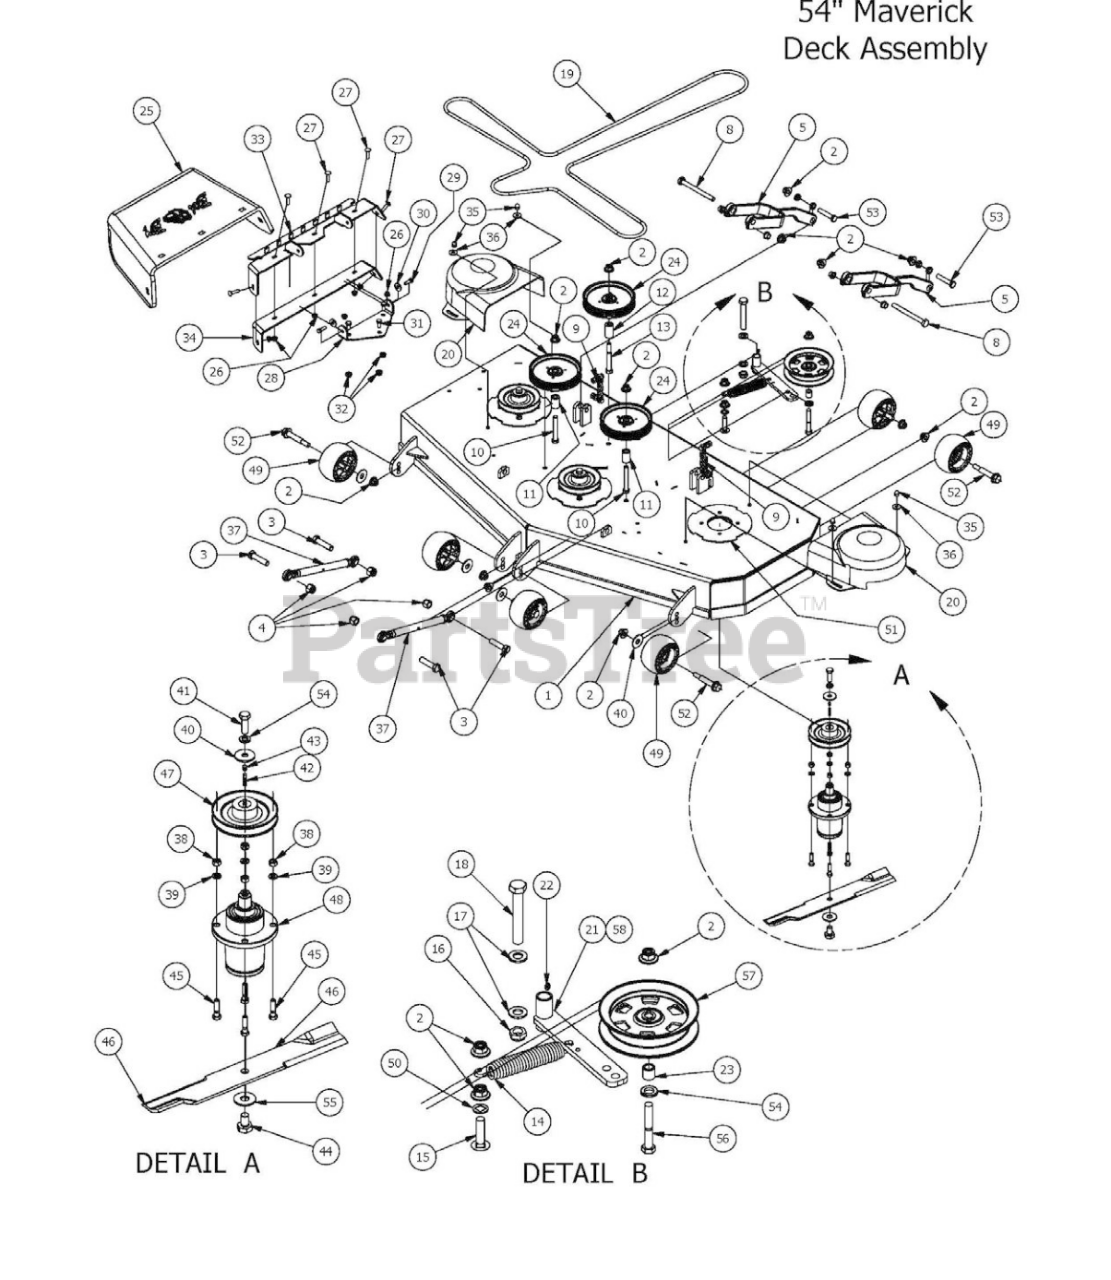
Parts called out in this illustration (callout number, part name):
1	Maverick 54" Deck
2	1/2-13 Nylon Flange Nut
3	5/8" x 2 1/2" Grade 5 Hex Bolt (Coarse)
4	5/8 Std NC Nylock Nut
5	Deck Arm Assembly
6	Flange Bushing For Lower Deck Arm
7	Flange Bushing For Upper Deck Arm
8	1/2" x 5 1/2" Bolt
9	6 Link Chain assembly
10	1/2 x 3 1/2 Flange Bolt Grade 8
11	Idler Pulley Standoff
12	1 3/4" Pulley Spacer
13	1/2" x 4" Bolt (Grade 8)
14	2015 Deck Idler Spring
15	1/2 x 2" Carriage Bolt
16	5/8-11 Nylon Insert Jam Half Nut
17	.630 ID Plastic Washer
18	5/8" x 4" Hex Bolt
19	B155.75 Deck Belt
20	2014 ZT Pulley Cover
21	Deck Idler
22	1/4" Drive in Grease Fitting
23	Spacer 3/4 OD x 1/2 ID x 314 Length
24	5-3/4 Idler Pulley
25	Rubber Discharge Chute
26	5/16" Nylon Flange Nut
27	5/16" x 1 1/4" Carriage Bolt
28	Discharge Chute Hanger (Deck Mounted)
29	5/16" x 1" Bolt
30	.360 ID Plastic Washer
31	3/8" x 3/4" Hex Bolt
32	3/8" Flange Nut
33	60" Discharge Chute Upper Hanger
34	60" Lower Hanger
35	Acorn nut-pulley Cover
36	.360 ID Plastic Washer-Black
37	Turnbuckle
38	3/8" Hex Nut
39	3/8" Lock Washer
40	1/2" Belleville Washer
41	1/2"-20 x 1 1/2 - Grade 5 Fine Thread Bolt
42	1/4" x 1" Key
43	5/16 Set Screw
44	5/8" x 1 1/2" Grade 8 Hex Bolt (Fine)
45	3/8" x 1 1/2" Hex Bolt
46	54" Deck Fusion Blade For Outlaw
47	5.25" Deck Spindle Pulley
48	Spindle Assembly
49	Anti-Scalp Roller
50	.517 Square Hole Round Washer
51	Deck Spindle Support Plate
52	Deck Wheel Bolt
53	1/2" x 3" Hex Bolt
54	1/2" Lock Washer Zinc
55	5/8" Flat Washer
56	1/2 x 2-3/4 Hex Bolt
57	5" Idler Pully
58	Deck Idler Assembly (Components 2,21,22,23,54,56,57)
